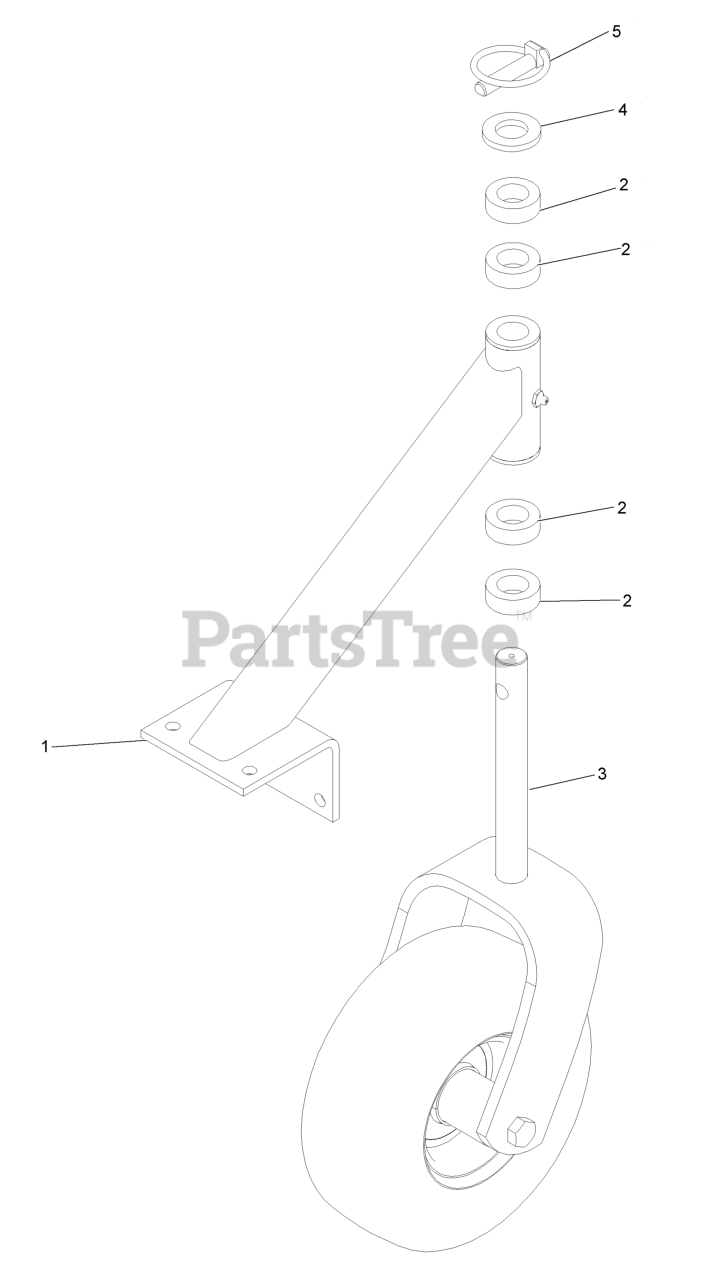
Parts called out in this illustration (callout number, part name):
1	ASM,CSTR SUPPORT W/WEIGHT
2	SPACER-CASTER
3	ASM,CASTER/WHEEL
4	WASHER-FLAT
